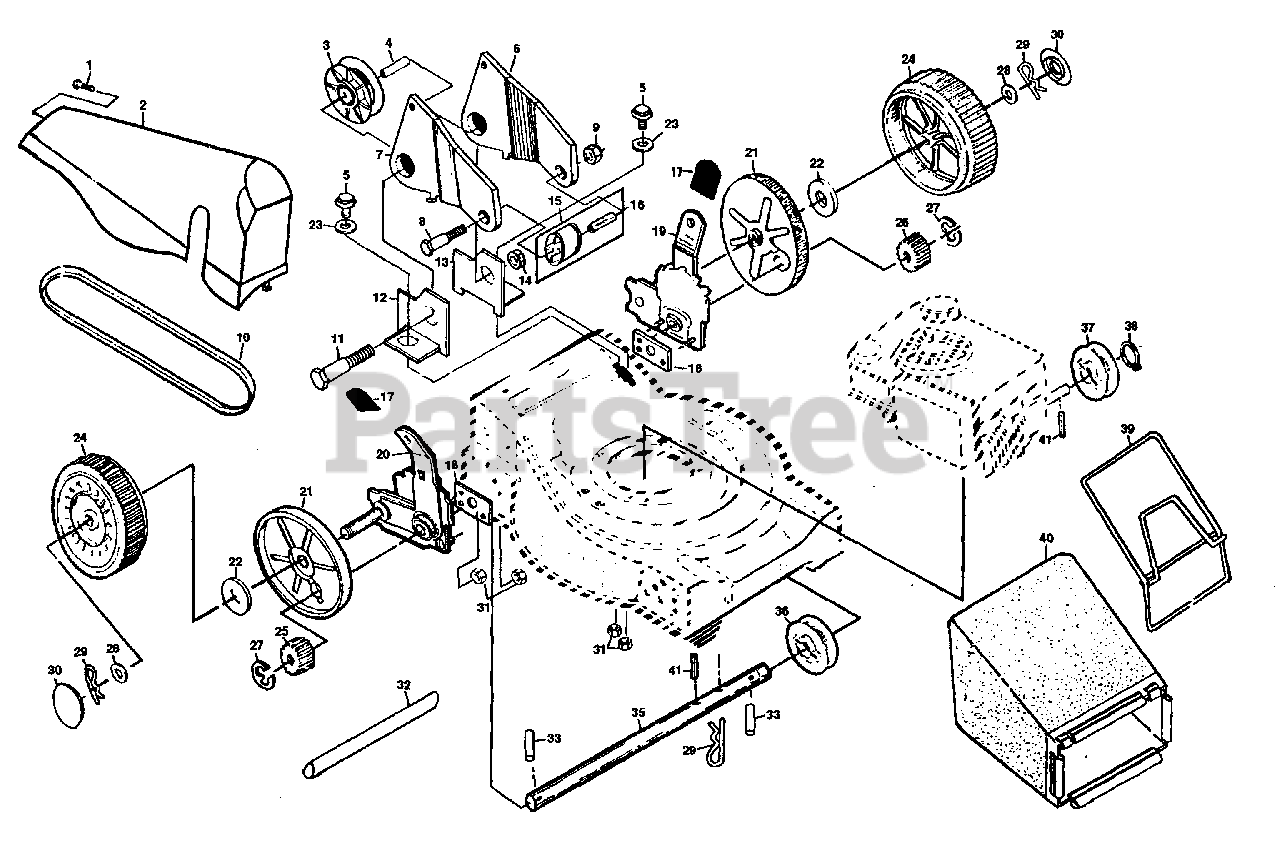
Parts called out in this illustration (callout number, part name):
1	Hex Washer Head Screw #10-24 x 1/2
2	Drive Cover
3	Idler Pulley
4	Pulley Spacer
5	Hex Head Machine Screw 1/4-20 x 3/4
6	Idler Bracket (Left)
7	Idler Bracket (Right)
8	Hex Head Bolt 1/4-20 x 1-1/2
9	Locknut 1/4-20
10	Drive Belt
11	Hex Head Bolt 5/16-18 x 1-1 /2
12	Pivot Bracket (Right)
13	Pivot Bracket (Left)
14	Locknut 5/16-18
15	Idler Assembly Kit
16	Idler Spacer
17	Selector Knob
18	Spacer Plate
19	Selector Assembly (Right)
20	Selector Assembly (Left)
21	Dust Cover
23	Flat Washer
24	Wheel & Tire Assembly 9.0 x 2.0
25	Drive Pinion (Right)
26	Drive Pinion (left)
27	E-Ring
28	Washer
29	Retainer Clip
31	Locknut 1/4-20
32	Drive Shaft Cover
33	Drive Pawl
35	Drive Shaft
36	Driven Pulley
37	Drive Pulley
38	Retaining Ring
39	Catcher Frame Assembly
40	Grass Bag Assembly
41	Dowel Pin
